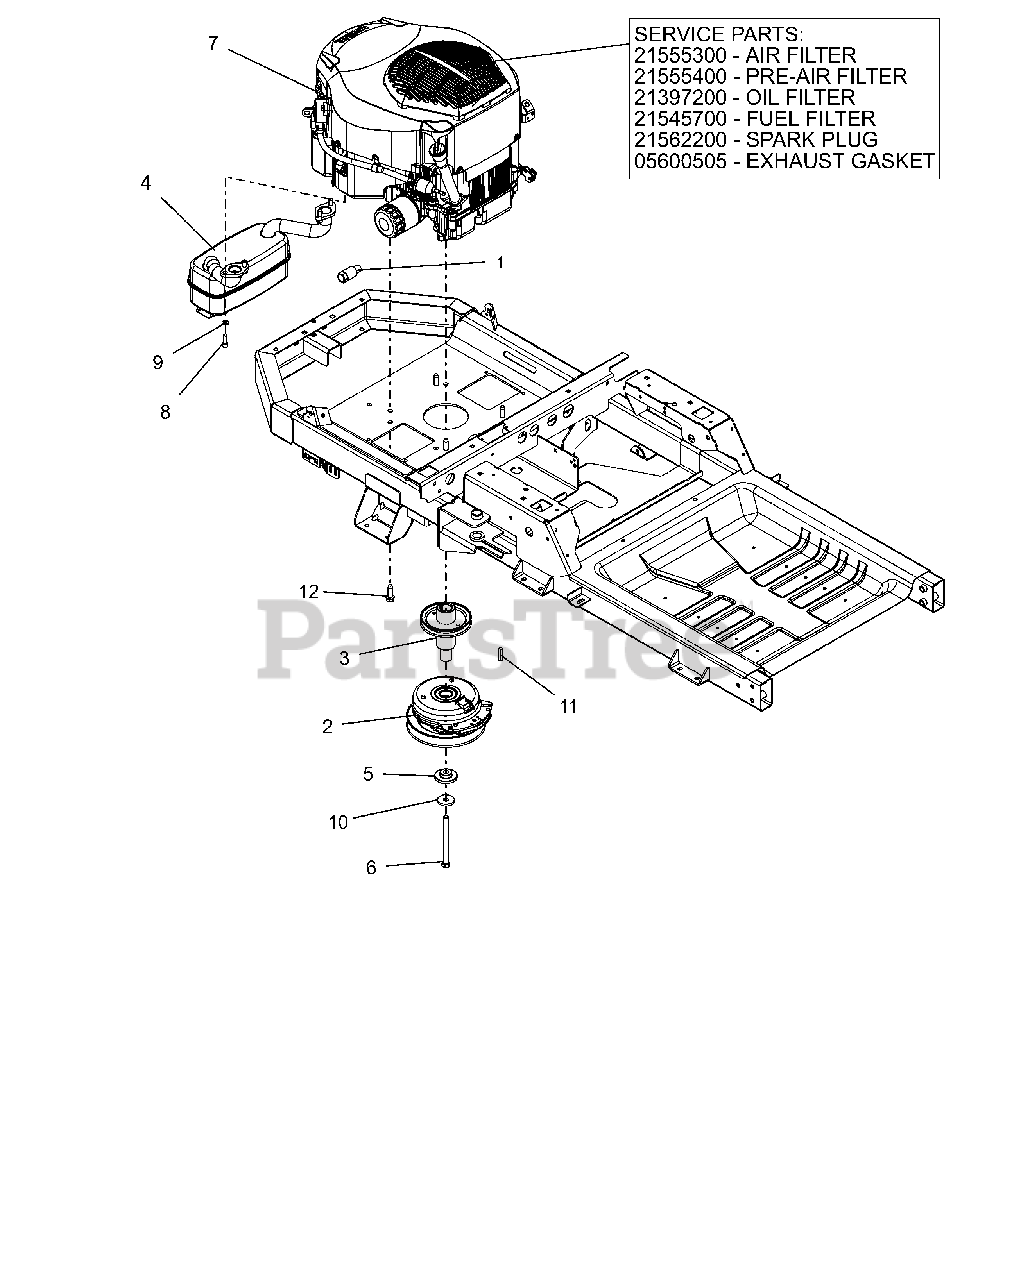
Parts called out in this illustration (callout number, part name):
1	DRAIN, OIL
2	CLUTCH,105FTLB MONOPOLE 6.83"
3	WLDMT, DRIVE SHEAVE (LG XL)CZC
4	MUFFLER - KOHLER
5	BSHG-FLG .469X1.06X.574X2.0
6	BLT-HEX.438-20X5 GR8 YZ NYTORQ
7	ENGINE-KOHLER PRO 24HP W/SC
7	AIR FILTER, KOHLER
7	PRE CLEANER, KOHLER
7	FILTER, OIL - KOH CV20
7	FILTER-FUEL KOHLER COURAGE PRO
7	PLUG, SPARK (RFI)
7	GASKET, MUFFLER KOHLER TWIN
8	SCR, SKH .312-18X.875 GR8 ZCC
9	WSHR,LK-REG .312X.078 ZCC
10	WASHER, 7/16" SPRING DISK
11	KEY-SQ .25 X 1.25 X .25 SAE
12	SCR,TAP .375-16X1.25HWH TR ZCC
